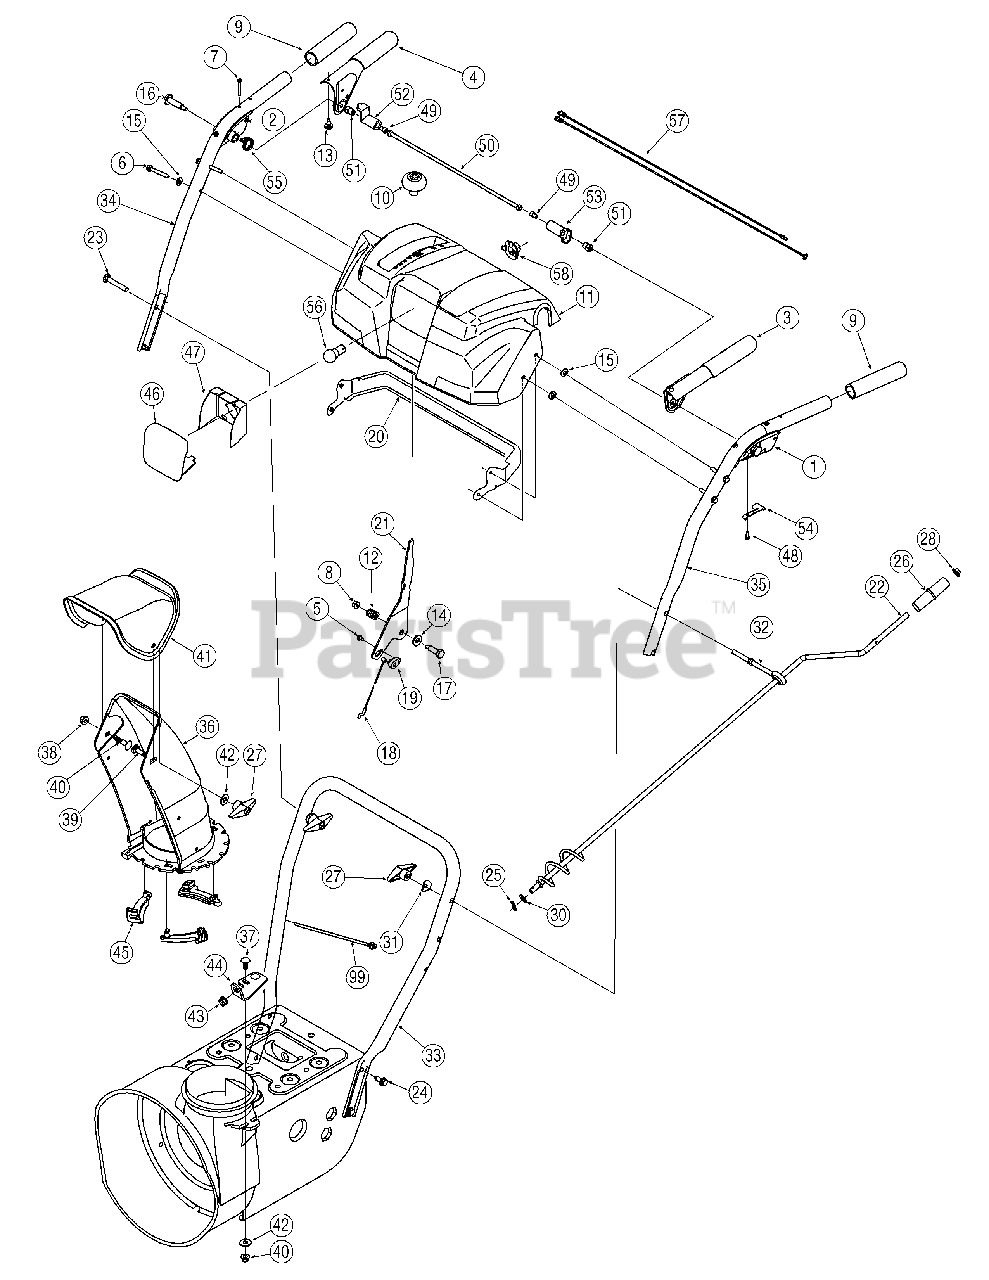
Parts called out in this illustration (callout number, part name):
1	Handle Assembly, Lock, LH
2	Handle Assembly, Lock, RH
3	Handle Ass’ y, Engagement LH
4	Handle Ass’y, Engagement, RH
5	Screw, #10-16, 0.500
6	Screw, 1/4-20, 1.750
7	Screw, Machine, #10-24, 1.375
8	Nut, Flange Lock, 1/4-20,
9	Grip, 1.0 ID x 5.0
10	Knob, Shift
11	Handle Panel, H-Style, Black
12	Spring, .39 x .60 x .88
13	Bumper, Rubber, .62 OD x .22
14	Washer, Flat, .385 x .870 x .092
15	Washer, Flat, .25 x .630 x .0515
16	Screw, Shoulder, .43 x 1.34, 1/4-20
17	Screw, Shoulder, .374 Dia. x 1.05
18	Cable, Speed Selector
19	Barrel Holder, Cable, LH
23	Screw, Carriage, 5/16-18, 2.25
24	Screw, 5/16-18, 0.75, Gr5
25	Pin, Cotter, .072 x 1.13
26	Crank Knob, 1.0 Dia. x 3.2, Black
27	Knob Assembly, Wing Nut, 5/16-18
28	Cap, Push, 3/8 Rod
29	Grommet, .44 ID x .94 OD x .50
30	Washer, Flat, .375 x .738 x
31	Washer, Saddle, 320 x .93
32	Eye Bolt, Chute Crank
36	Chute, Lower, 5.0 Diameter
37	Bolt, Carriage, 5/16-18, 1.0
38	Nut, Flange Lock, 5/16-18, Nylon
39	Bolt, Carriage, 5/16-18, 1.0
40	Bolt, Carriage, 5/16-18, .750
41	Chute, Upper, w/ Label
42	Washer.349 ID x .879 OD
43	Bushing, Plastic, .380
45	Flange Keeper, Chute
47	Reflector Label, Lens
48	Screw, #8-16 x 0.50
49	Screw, 1/4-20 x.375
50	Pivot Rod
51	Shoulder Nut, 1/4-20
52	Lock Plate
53	Clutch Lock Cam
54	Clutch Lock Spring
55	Torsion Spring
56	Lamp
57	Wire Harness, Lamp
58	Light Socket
